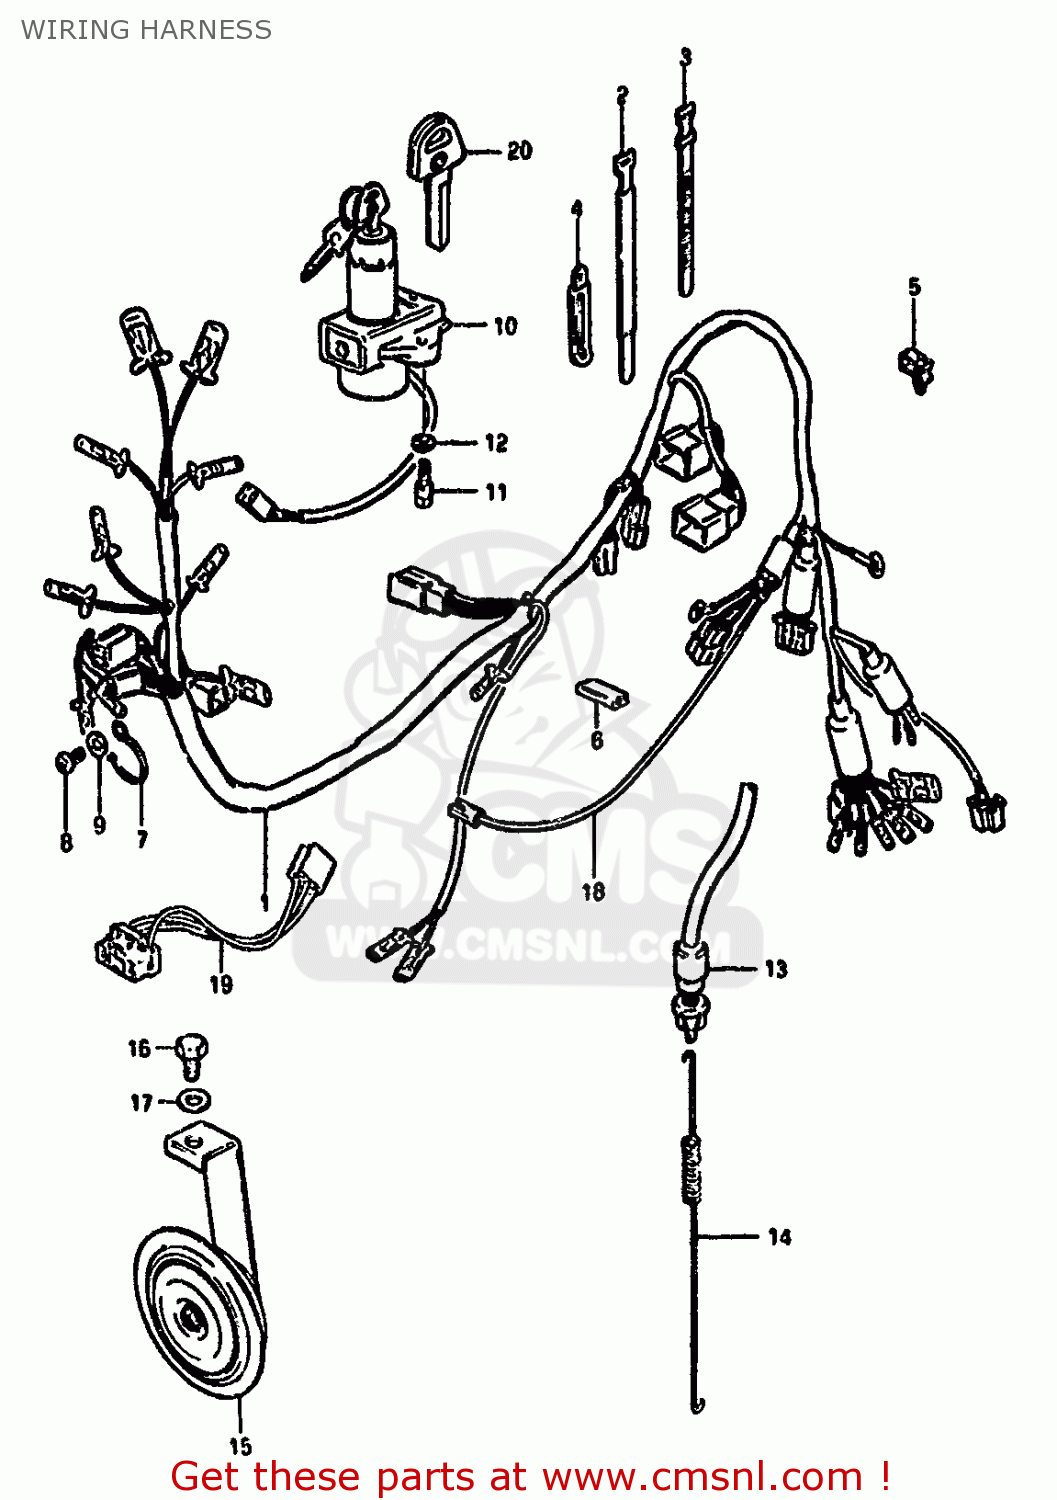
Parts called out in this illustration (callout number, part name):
1	WIRING HARNESS
2	CLAMP
3	CLAMP(L:120)
4	CLAMP
5	CLIP
6	PROTECTOR,WIRING HARNESS
7	GUIDE,WIRING HARNESS
8	SCREW 6X12
9	WASHER
10	LOCK ASSEMBLY,STEERING
11	BOLT
12	LOCK WASHER
13	SWITCH ASSEMBLY,BRAKE LAMP
14	SPRING
15	HORN
16	BOLT 8X12
17	WASHER
18	WIRE
19	LEAD WIRE,HEADLAMP
20	KEY,BLANK
